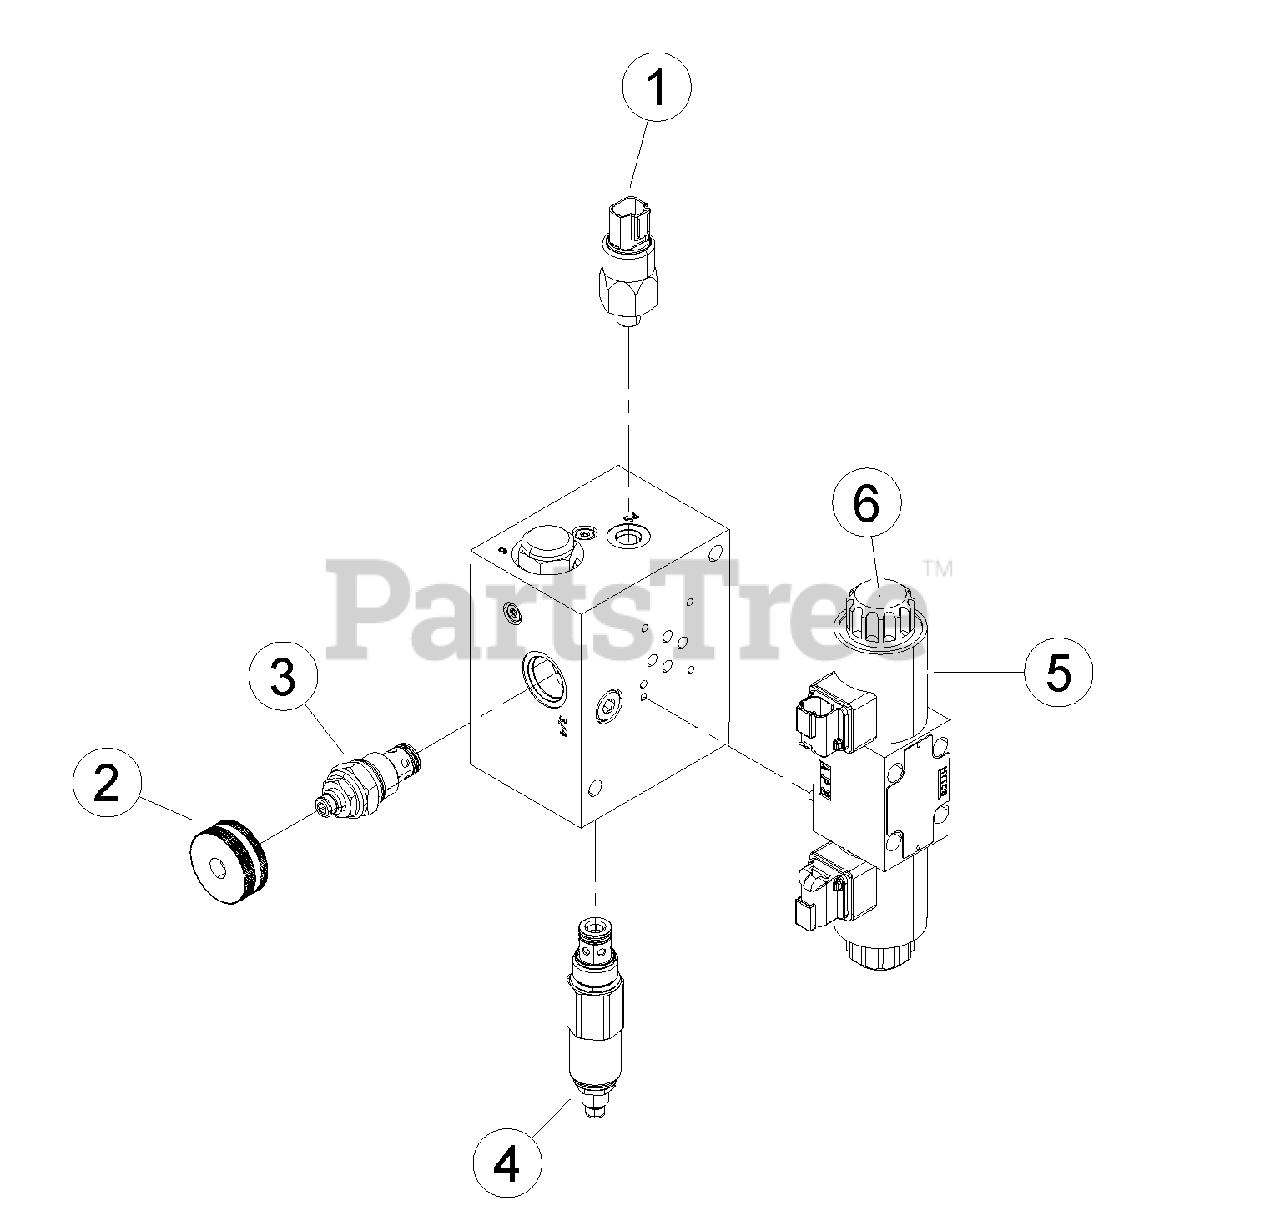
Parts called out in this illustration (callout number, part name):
1	SWITCH, PRESSURE GC
2	KIT, VALVE KNOB
3	VALVE, NEEDLE - 10 MOUNT
4	VALVE, DIFFERENTIAL SENSING
5	COIL, SOLENOID
6	NUT, COIL SOLENOID
